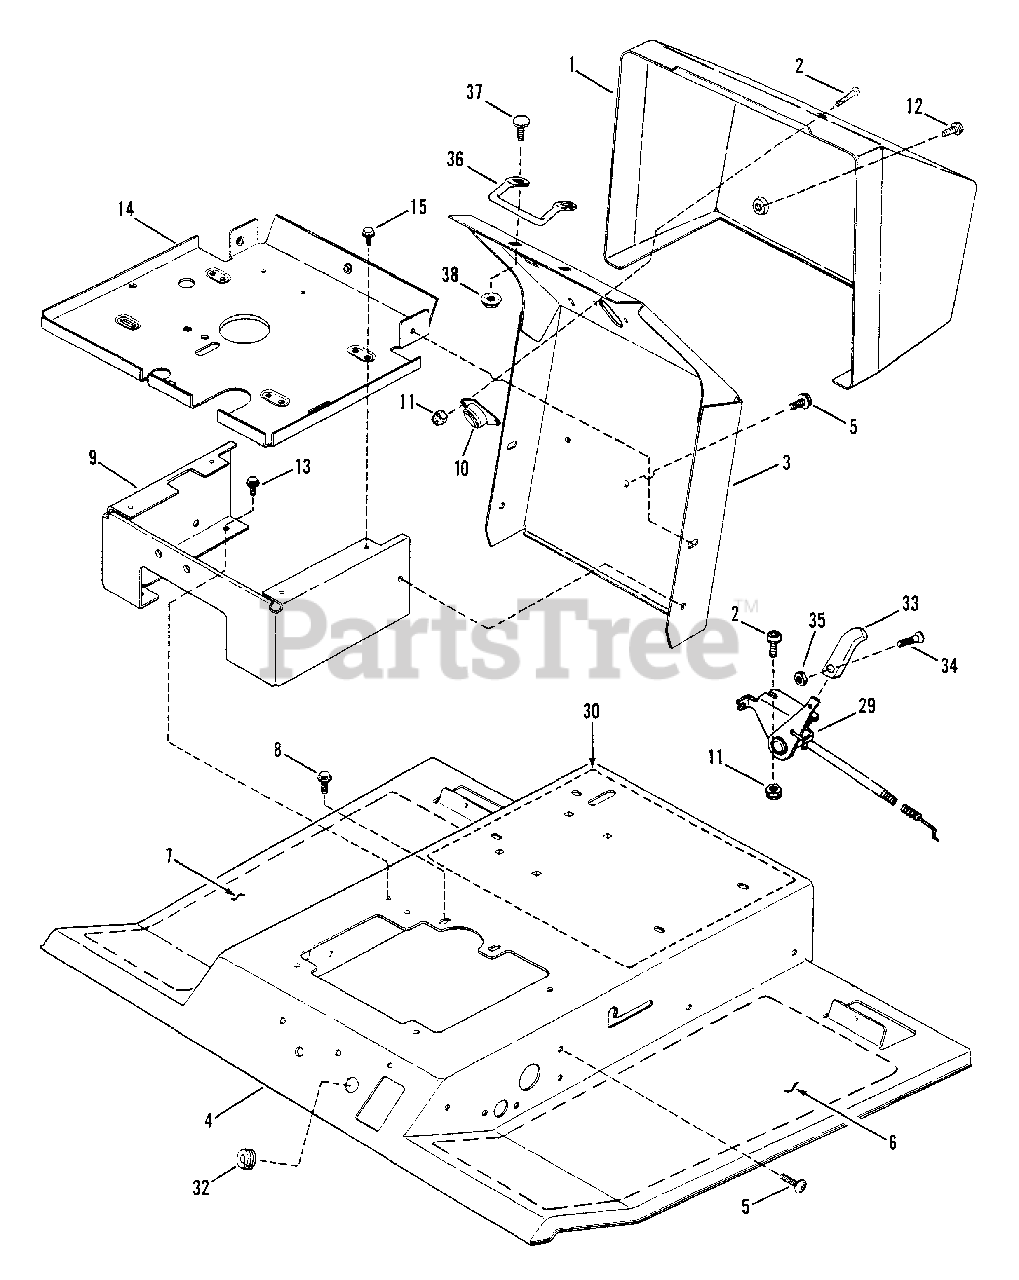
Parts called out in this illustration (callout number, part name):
1	PANEL, Dash
2	SCREW, 1/4-20 x 1" Phillips
3	SUPPORT, Steering Shaft
4	CHANNEL, Foot Rest
5	SCREW, 5/16-18 x 7/8" Self-Tapping
6	TREAD, Left Side (Non-Skid)
7	TREAD, Right Side (Non-Skid)
8	SCREW, 5/16-18 x 5/8" Self-Tapping
9	MOUNT, Fuel Tank/Battery
10	ASSEMBLY, Steering Shaft Flange
11	NUT, 1/4-20 Hex
12	SCREW, #10-24 x 1/2" Self-Tapping
13	SCREW, 5/16-18 x 1/2" Self-Tapping
14	PLATE, Fuel Tank & Battery Mount
15	SCREW, 1/4-20 x 1/2" Self-Tapping
29	CONTROL, Throttle
30	DECAL, Caution & Instruction
32	GROMMET, 5/16" I.D. x 1" O.D. Split
33	HANDLE, Throttle Control
34	SCREW, #8-32 x 3/8" Fillister Head
35	NUT, #8-32 Hex
36	ROD, Hood Latch
37	BOLT, 1/4-20 x 5/8" Flat Head Carriage
38	NUT, 1/4-20 Hex Flange Lock
